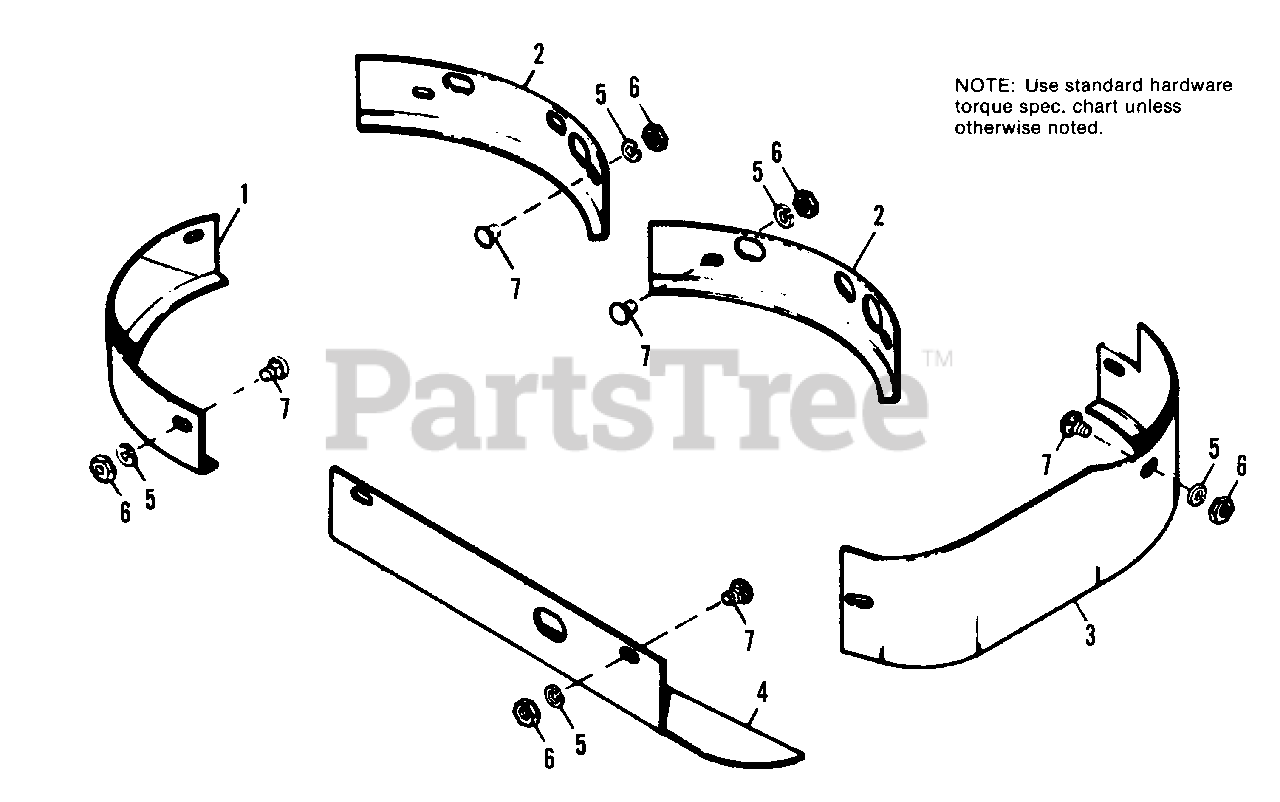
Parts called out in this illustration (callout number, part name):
1	BAFFLE, Front, R.H.
2	BAFFLE, Rear, Center
3	BAFFLE, L.H.
4	BAFFLE, Front, Center
5	LOCKWASHER, 5/16
6	NUT, Hex, Full, 5/16-18
7	BOLT, Carriage, 5/16-18 x 1/2
